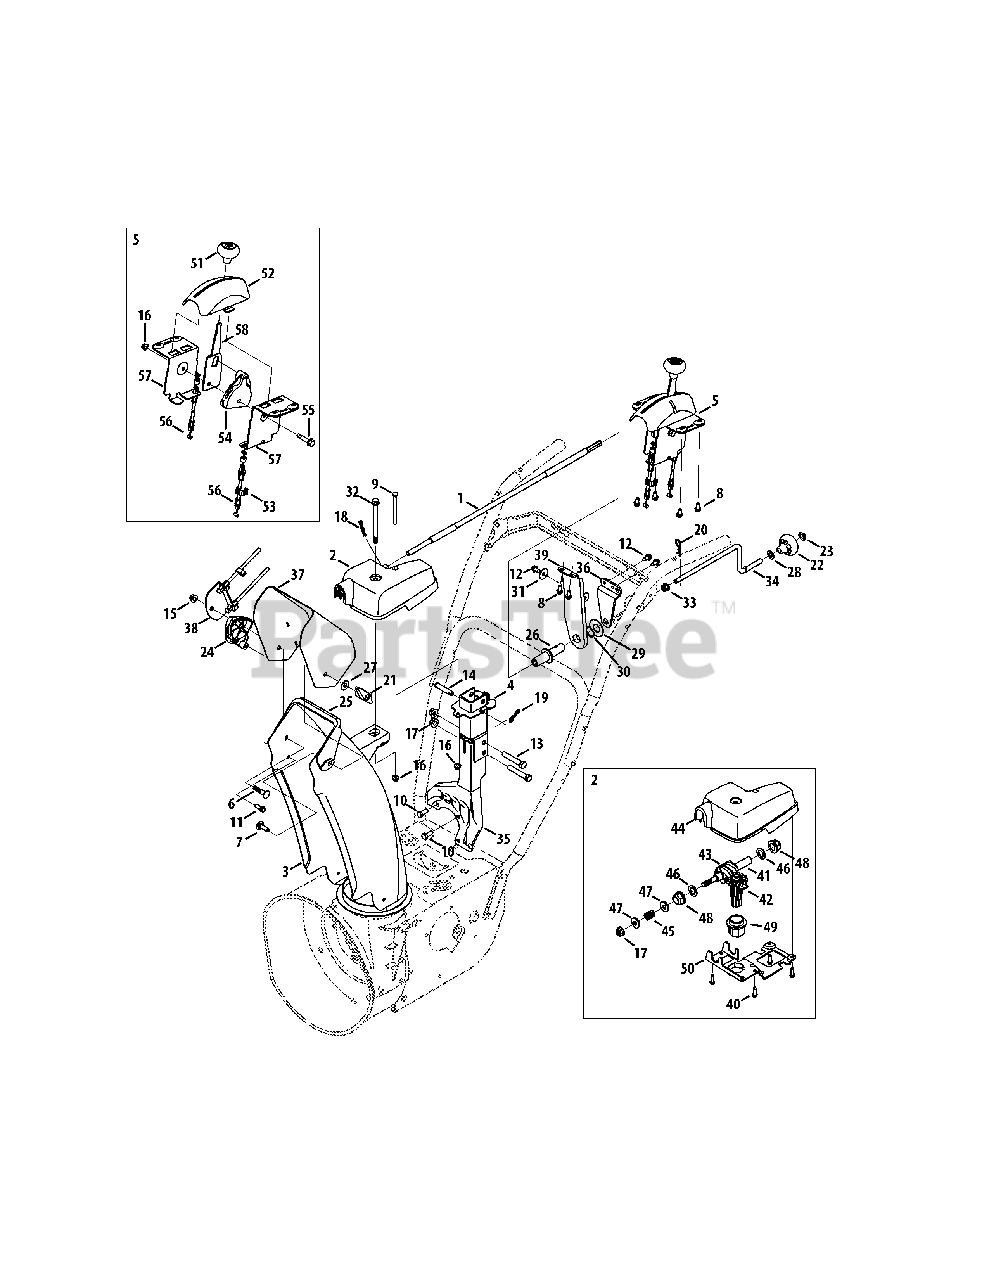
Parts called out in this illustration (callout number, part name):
1	Control Assembly
2	Chute Rotation Gearbox
3	Chute, Lower
4	Support Bracket Extension
5	Chute Control, 2-Way
6	Bolt, Carriage, 5/16-18 x 1.50
7	Bolt, Carriage, 5/16-18 x 1.00
8	Screw, HL, 1/4-15 x 0.50
9	Hex Head Screw, 1/4-20 x 3.00
10	Hex Head Screw, 5/16-24 x .750
11	Screw, HL, 1/4-15 x 0.750
12	Hex Washer Screw, 1/4-20 x .625
13	Hex Cap Screw, 3/8-16 x 2.25
14	Clevis Pin, 3/8 x 1.87
15	Nut, Flangelock, 5/16-18
16	Nut, Flangelock, 1/4-20
17	Flange Lock Nut, 3/8-16
18	Internal Cotter Pin
19	Bow-Tie Cotter Pin
20	Internal Cotter Pin
21	Wing Knob, 5/16-18
23	Push Cap, 3/8
24	Chute Cable Guide
25	Chute Adapter
26	Chute Control Rod Coupling
27	Washer, Flat, .349 x .879
28	Flat Washer, .375 x .738 x .063
29	Flat Washer, .78 x 1.59 x .06
30	Washer, Wave, .785 x 1.0 x .012
31	Flat Washer, .265 x 1.00 x .030
32	Screw, Shoulder, .312 x 3.5 x 1/4-20
33	Plastic Bushing, .38
35	Chute Support Bracket
36	Support Rod Bracket
37	Chute, Upper
38	Cable bracket
39	Chute Control Support Bracket
40	Screw, 12-16 x .75
42	Gear Assembly
43	Worm
45	Compression Spring, .39 x .60 x .88
46	Flat Washer, .625 x 1.0 x .067
47	Flat Washer, .380 x .93 x .110
48	Hex Bearing
49	Flange Bearing
50	Gear Bracket
51	Shift Knob
52	Cover, Tilt Cover
53	Cable Clip
54	Chute Tilt Cable Guide
55	Screw, Shoulder, .31 x .995:1/4-20
56	Cable, Chute Tilt
57	Bracket, Mounting
